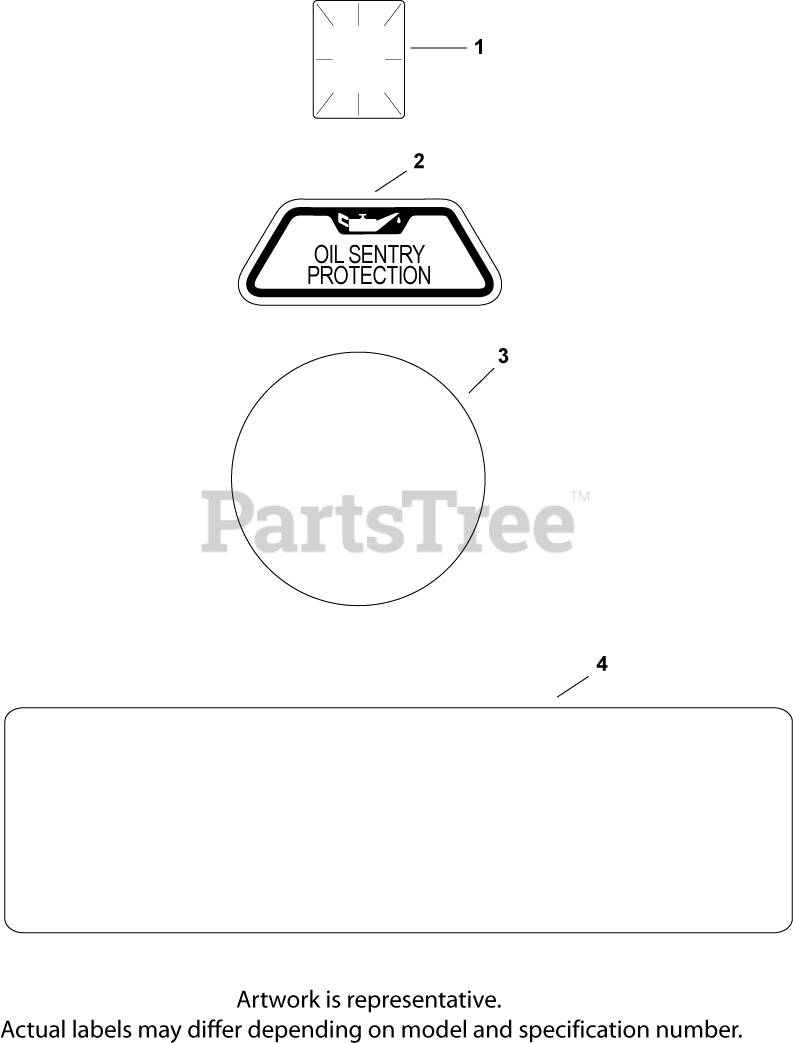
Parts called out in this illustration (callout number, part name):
1	DECAL, CLEAR LAMINATE USE 25 113 70-S
2	DECAL, OIL SENTRY - (#DSC)
3	DECAL, GRASS SCREEN USE 24 113 499-S
4	DECAL, 20 HP - DISCONTINUED
